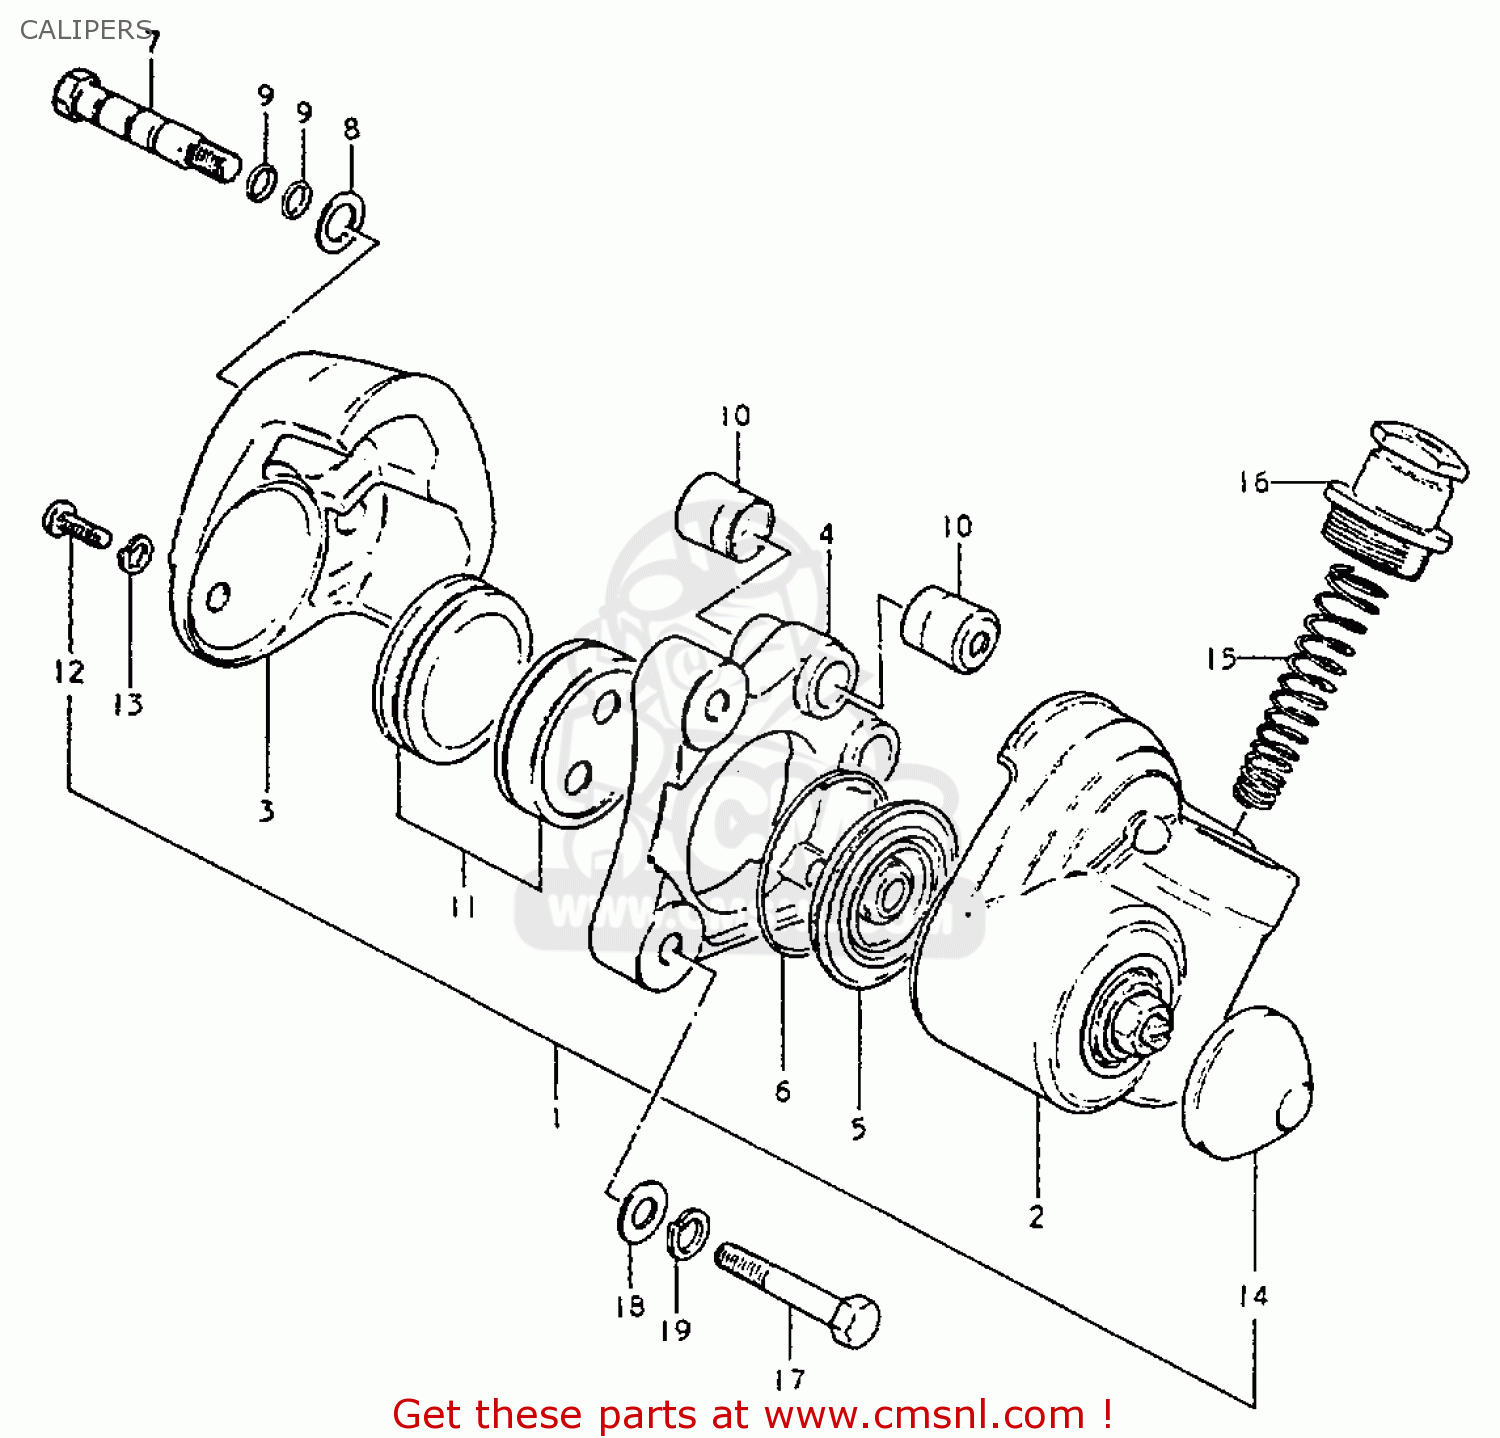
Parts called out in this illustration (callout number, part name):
1	CALIPERS ASSY
2	HOUSING, CALIPAS NO.1
3	HOUSING, CALIPAS NO.2
4	HOLDER, CALIPAS
5	BOOT
6	CLIP
7	AXLE
8	WASHER
9	O RING,CALIPER AXLE
10	COVER,AXLE DUST
11	PAD SET,BRAKE (MCA)
12	SCREW
13	LOCK WASHER
14	BOOT
15	SPRING, LEVER RETURN
16	PLUG
17	BOLT
18	WASHER
19	WASHER,LOCK,8.
